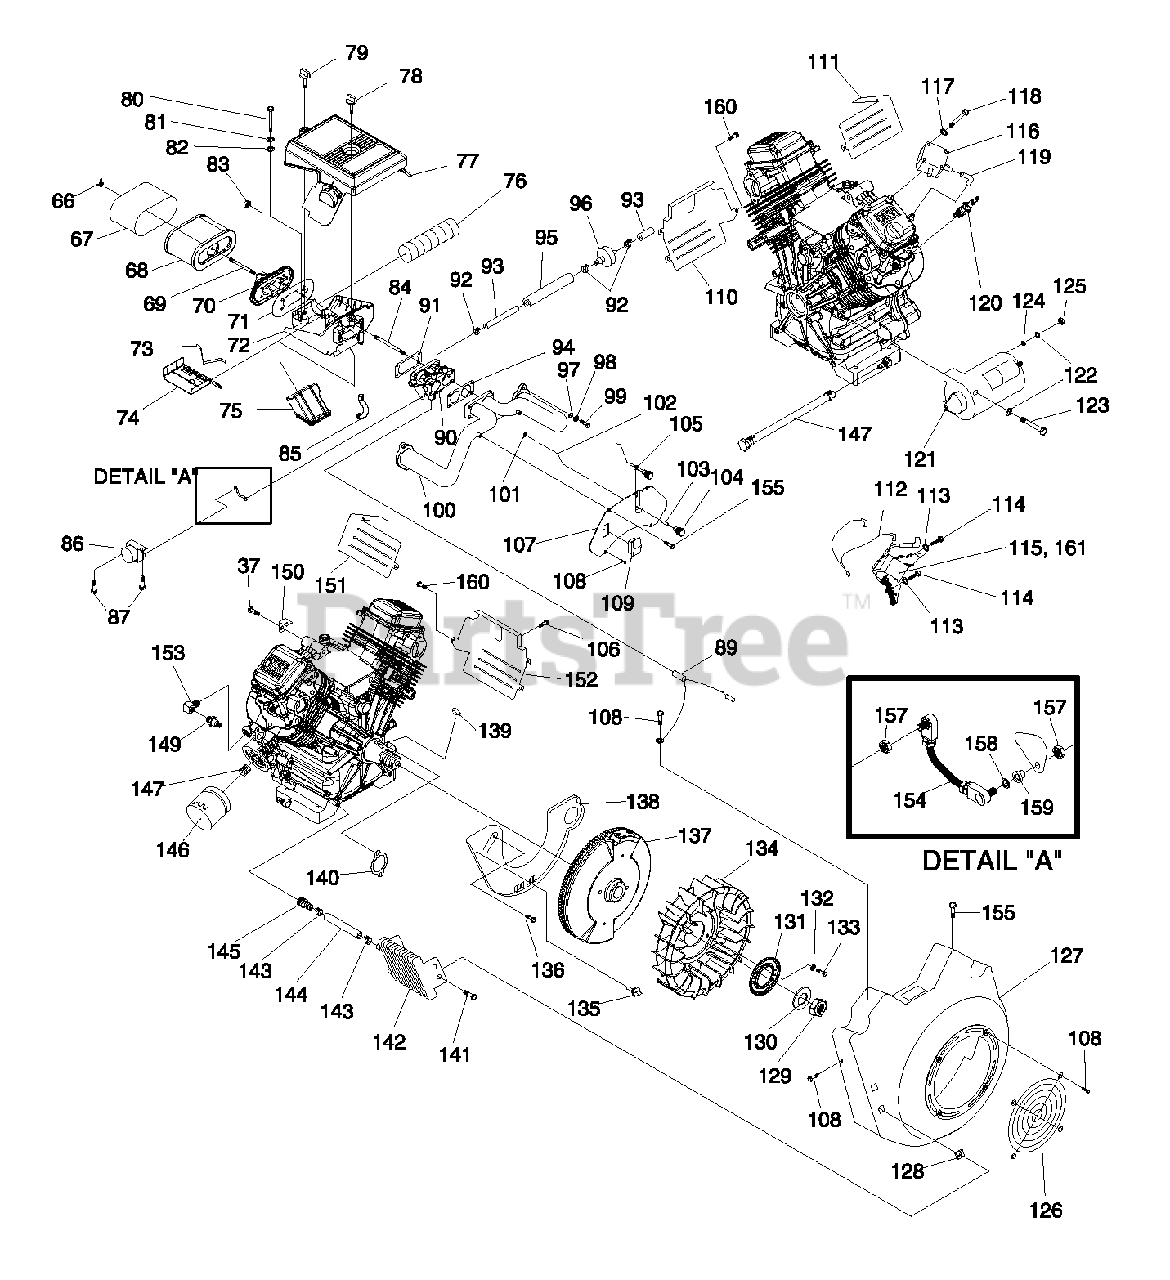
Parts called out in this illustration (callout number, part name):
66	WINGNUT, AIRBOX
67	PRECLEANER, AIR
68	ELEMENT, AIR CLEANER
69	STUD M6-1.0 X 73
70	ADAPTOR, SPIT BACK
71	GASKET, SPITBACK
72	BASE, AIRBOX (GT-990)
73	SPRING, WINTER/SUMMER VALVE
74	VALVE, SUMMER / WINTER
75	SNORKEL, AIR INTAKE
76	TUBE, HEAT RISER 50.8 I.D.
77	COVER, AIRBOX
78	KNOB, AIRBOX 17mm
79	KNOB, AIRBOX 95MM
80	SCREW HHC M6-1.0 X 35
81	WASHER LOCK M6-1/4
82	WASHER FLAT 1/4
83	NUT LOCK FLANGE M6-1.0
84	STUD, METRIC
85	HOSE, BREATHER
86	CONTROLLER ASSEMBLY
87	SCREW HHTT M5-0.8 X 10
89	ASSEMBLY, WIRE
90	CARBURETOR (GT-990)
91	GASKET, CARB TO SPACER (GT-990)
92	CLAMP HOSE BAND 1/4
93	HOSE1/4 ID
94	GASKET, MANIFOLD TO CARB (GT-990)
95	SLEEVING 1/2" I.D.
96	FILTER, FUEL
97	WASHER FLAT M8
98	WASHER LOCK M8
99	SCREW SHC M8-1.25 X 30
100	MANIFOLD, INTAKE
101	NUT HEX M3-0.5
102	ROD, SUMMER / WINTER VALVE
103	BUSHING, MINI CONTROL PANEL
104	KNOB, CONTROL SUMMER / WINTER
105	CHOKE ASSEMBLY
106	SCREW TAPTITE M5-0.8 X 8 ZP
107	PANEL, CONTROL FACE PLATE
108	SCREW TAPTITE M6-1.0X 10 YELLOW CHROME
109	SWITCH ROCKER
110	WRAPPER, LOWER CYLINDER 2
111	WRAPPER, UPPER CYLINDER 2
112	ASSEMBLY, GROUND WIRE
113	WASHER LOCK M6-1/4
114	SCREW TAPTITE M6-1.0 X 25 BP
115	ASSY, IGN COIL W/DIODE NO ADV
116	PUMP, IMPULSE
117	WASHER LOCK M4
118	SCREW PPHM M4-0.7 X 40
119	ELBOW, RUBBER 90 DEG.
120	SPARKPLUG, CHAMPION RC14YC
121	STARTER, DELCO REMY SD80
122	WASHER LOCK M8-5/16
123	SCREW HHC M8-1.25 X 85 G8.8
124	WASHER, FLAT M8
125	NUT, HEX M8-1.25 G8
126	GUARD,FAN
127	HOUSING, BLOWER GASOLINE COOLER
128	NUT, GROMMET 1/4 PLUG
129	NUT,HEX M24
130	WASHER, M24
131	PLATE, FAN
132	WASHER SHAKEPROOF INT M8 SS
133	SCREW HHC M8-1.25 X 12 G8.8
134	FAN, NYLON
135	ASSY,GROUND WIRE CONNECTOR
136	SCREW TAPTITE M6-1X10 YELLOW CHROME
137	FLYWHEEL ASSEMBLY
138	PLATE, BACKING GT990 WITH OIL COOL
139	KEY, WOODRFF 4 X 19D
140	GASKET, MANIFOLD / PORT
141	PLASTITE,1/4-15 X 3/4
142	COOLER, OIL
143	CLAMP HOSE .38-.87
144	HOSE, 3/8" I.D. X 6" LONG
145	BARBED STR 1/4NPT X 3/8 WITH VIBRA SEAL
146	OIL FILTER
147	NIPPLE, 3/4"-16 UNF
148	ASSEMBLY, OIL DRAIN HOSE
149	SWITCH, OIL PRESS
150	BRACKET, AIRBOX SUPPORT
151	WRAPPER, UPPER CYLINDER 1
152	WRAPPER, LOWER CYLINDER 1
153	BRASS ST ELBOW 1/4 NPT
154	ASSY, ROD, GOV. STEPPER MOTOR
155	SCREW HHHC M6-1.0 X12
157	NUT, LOCK HEX M3-0.5 (GT-990)
158	WASHER FLAT #4 (GT-990)
159	SPACER, ROD (GT-760 ONLY)
160	SCREW HHFC M6-1.0 X 10mm
161	ASSY, IGN COIL W/DIODE NO ADV
